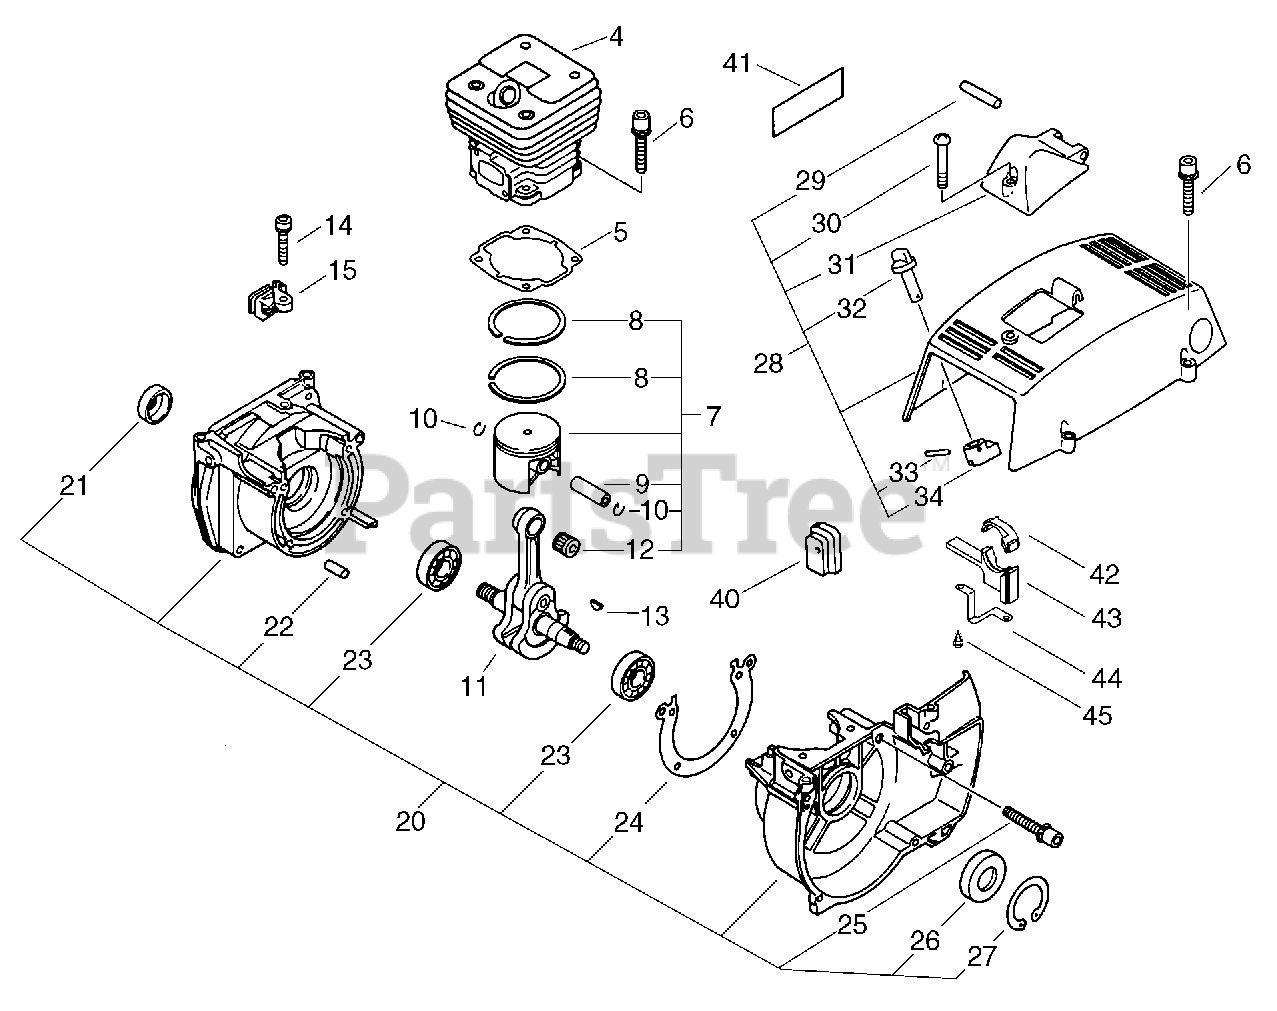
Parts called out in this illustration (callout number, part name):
4	CYLINDER
5	GASKET, CYLINDER
6	SCREW - 5X22
7	PISTON KIT
8	RING, PISTON
9	PIN, PISTON
10	RING, RETAINING
11	CRANKSHAFT ASSY
12	BEARING, NEEDLE
13	KEY - 3X14
14	SCREW - 5X16
15	BRACKET, THROTTLE CABLE
20	CRANKCASE KIT
21	SEAL, OIL
22	PIN - LOCATING
23	BEARING, BALL - 6202
24	GASKET, CRANKCASE
25	SCREW - 5X35
26	SEAL, OIL
27	RING, RETAINING - 35
28	COVER, CYLINDER
30	SCREW - 5
31	COVER, PLUG CAP
32	ROD, CHOKE
33	PIN - SPRING -- 2X10
34	END, LEVER
41	LABEL - MODEL
44	BRACKET
45	SCREW - 4X16
